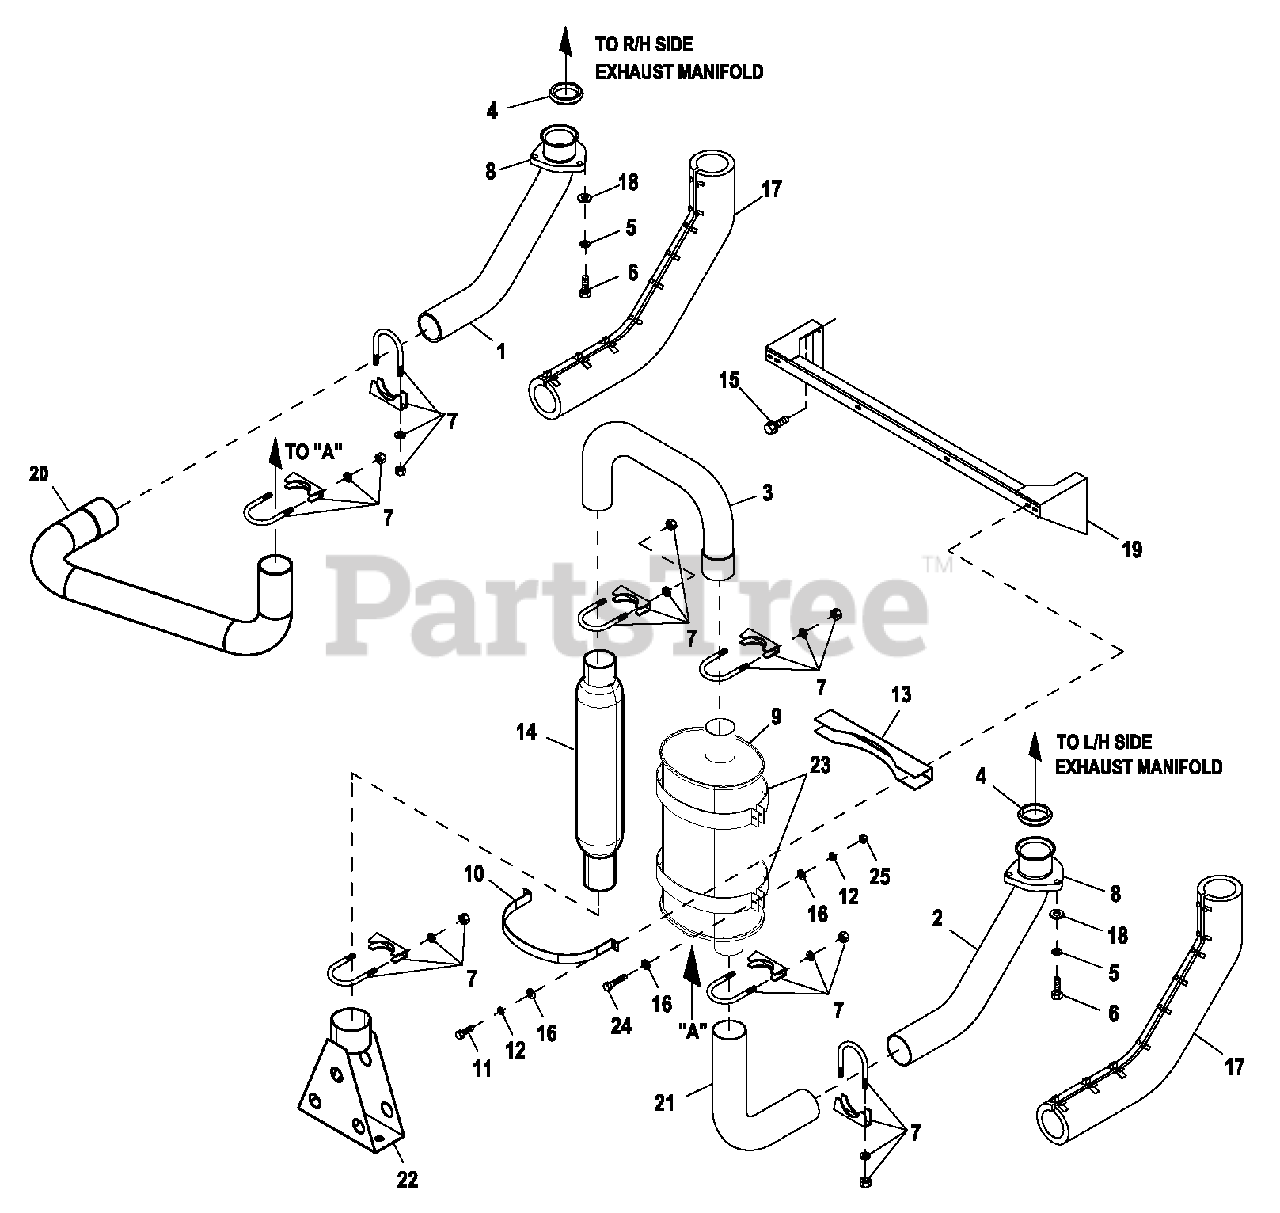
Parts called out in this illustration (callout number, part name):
1	PIPE, EXH MANIFOLD 5.4L C2 RH (6.8L 70KW)
2	PIPE, EXH MANIFOLD 5.4L C2 LH (6.8L 70KW)
3	PIPE, EXHAUST MUFFLER OUT
4	RING GASKET, 2.5DIA
5	WASHER LOCK M10 SS
6	SCREW HHC M10-1.5X 50 SS FTH
7	B OLT U 3/8-16X2.62
8	FLANGE, EXHAUST
9	MFLR 7" X 9" X 25" (2) 2.5" IN/2.5" OUT
10	MUFFLER STRAP
11	SCREW HHC M6-1.0 X 25 C8.8
12	WASHER LOCK M6-1/4
13	MUFFLER BRACKET STIFFENER
14	MUFF SEC 23.5" X 2.55IN/2.5OUT
15	SCREW HWHT M6-1 X 16 N WA Z/JS
16	WASHER FLAT 1/4-M6 ZINC
17	EXHAUST BLANKET 737MM (6.8L 70KW)
18	WASHER FLAT 3/8 SS
19	BRACKET MUFFLER
20	PIPE, EXHAUST RH CPL C2
21	PIPE EL B OW EXHAUST MUFFLER
22	DIFFUSER EXHAUST WELDMENT
23	MUFFLER STRAP UPPER/LOWER
24	SCREW HHC M6-1.0 X 35 C8.8 CLR
25	NUT HEX M6-1.0 G8 CLEAR ZINC
